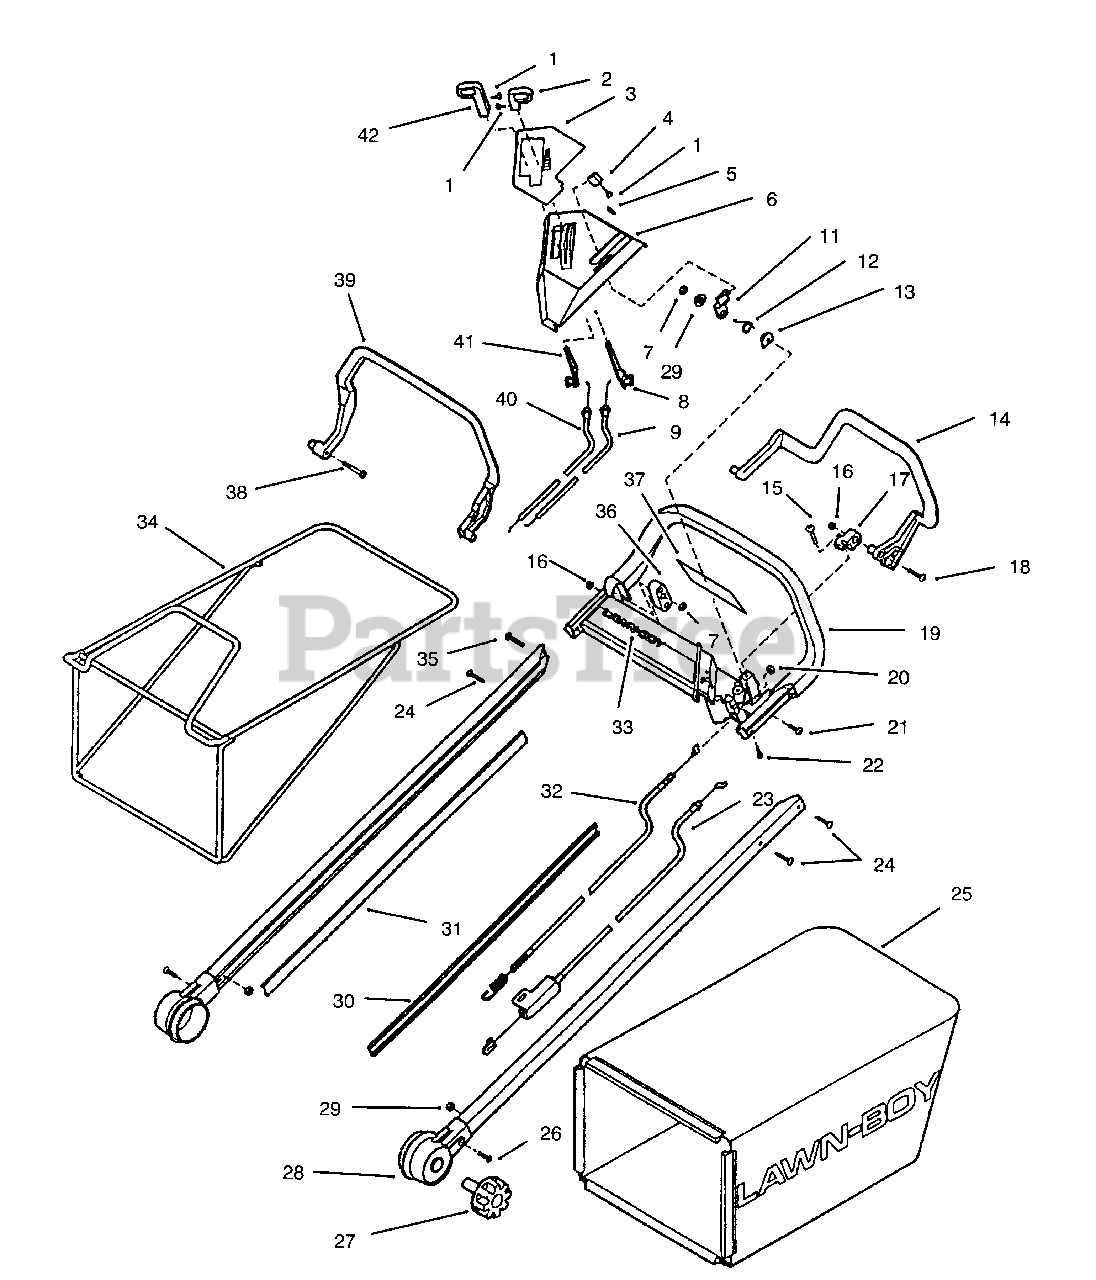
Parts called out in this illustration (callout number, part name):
1	Screw-Set
2	Assembly-Knob, Throttle (Incl. Ref. #1)
3	Plate-Logo
4	Assy.-Knob, BBC Latch (Incl. Ref. #1)
6	Assembly-Cover, Upper (Incl. Ref. #3)
8	Lever-Throttle
9	Assembly-Cable, Throttle
11	Lever-Latch, BBc
14	Bail-Self-propelled
17	Pivot-Bail
19	Assembly-Handle & Decal (Incl. Ref. #24, 33 & 37)
20	Nut-Cable, Self-propelled
23	Assy.-Cable, BBC
24	Screw-Thread Forming
25	Bag-Rear, Grass
27	Knob-Mounting, Handle
28	Assembly-Shaft, Handle (Incl. Ref. # 26 & 29)
30	Insert-Handle, Cable Side
31	Insert-Handle
32	Assy.-Cable, Self-propelled
33	Decal-Lawn-Boy
36	Block-Bail
37	Decal-Warning
39	Bail-Brake,Engine
40	Assy.-Cable, Gear Select
41	Lever-Gear, Select
42	Assembly-Knob (Incl. Ref. #1)
